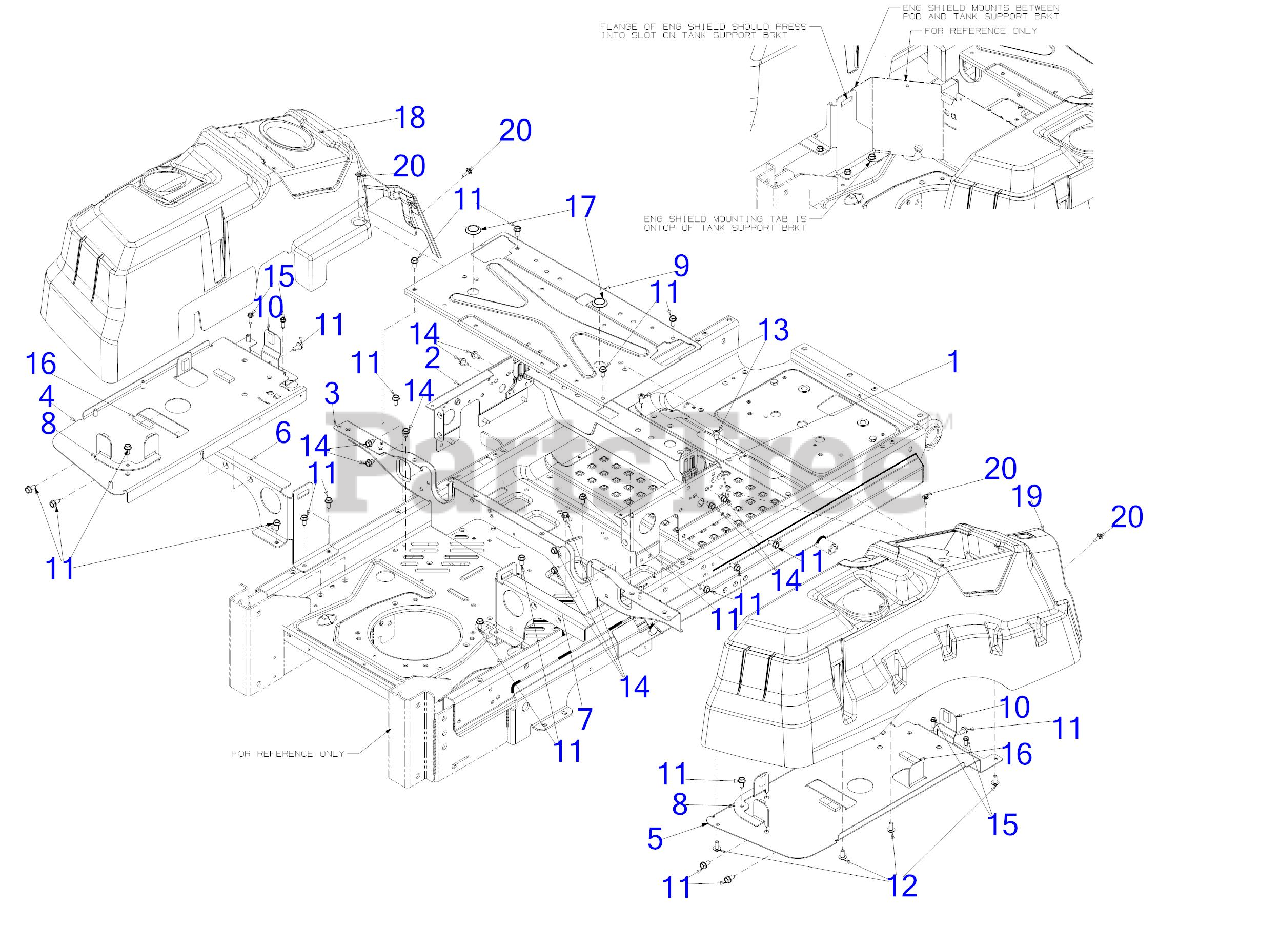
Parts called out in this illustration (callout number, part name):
11	SCREW 5/16-18 x .750
12	SCREW 5/16-14 x .750
13	SCREW 5/16-18 x .750
14	SCREW 5/16-18 x .500
15	SCREW 1/4-20 x .750
16	FOAM TAPE .625 WIDE x .25 THK BULK
18	CONSOLE (LH) Z-STYLE
19	CONSOLE (RH) Z-STYLE
20	SHOULDER SCREW M6-1 .368 X.115
